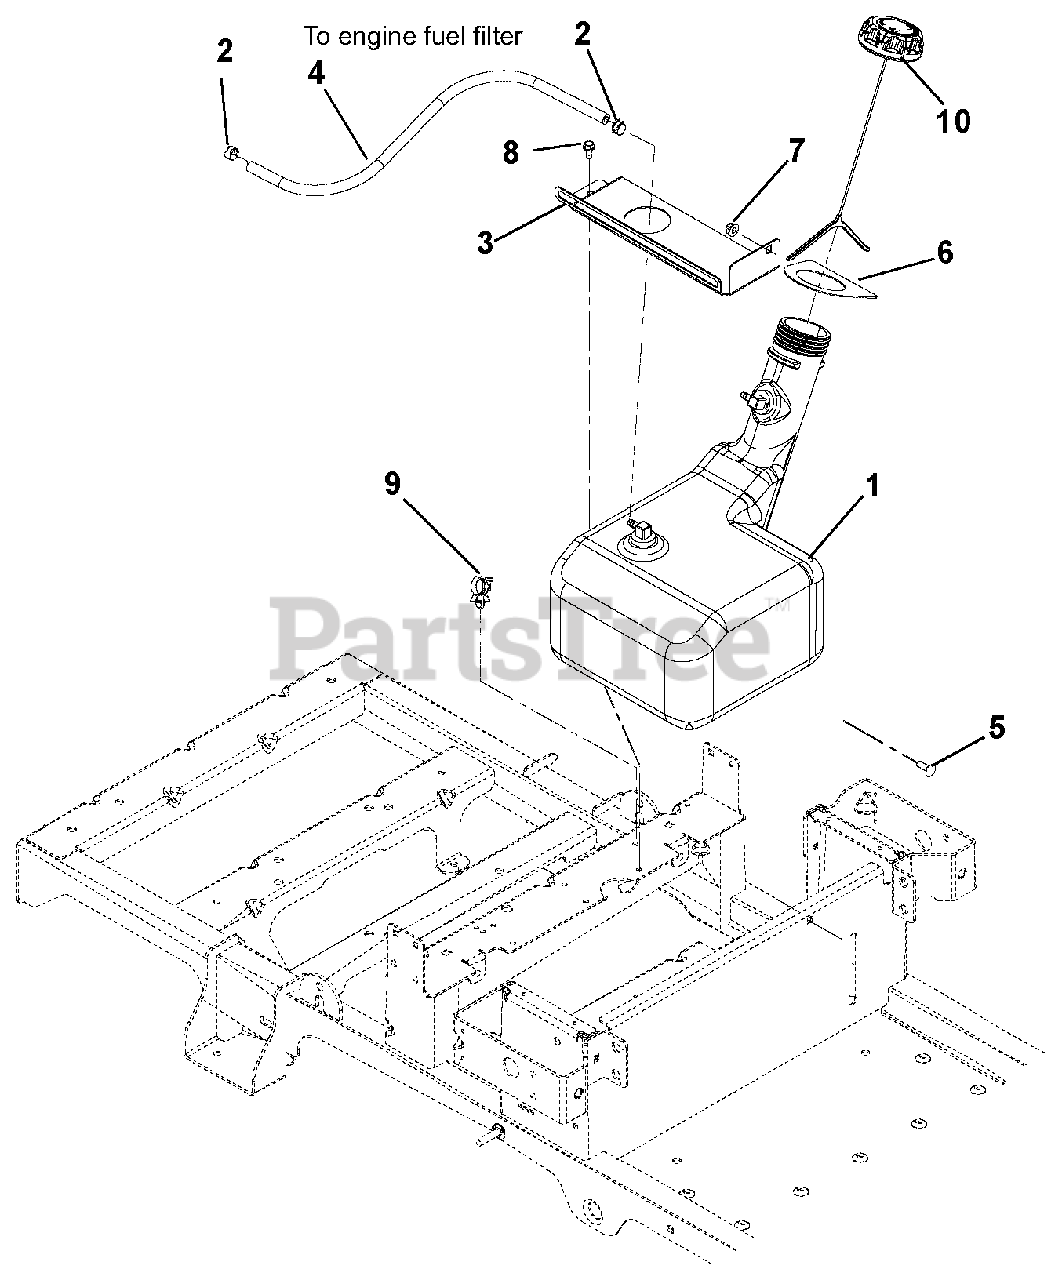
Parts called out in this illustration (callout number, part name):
1	FUEL TANK SUB ASSY ZT/ZOOM/WAW
1	TANK, ZOOM/WAW NON-PERM. FUEL
1	FUEL PICK UP TUBE
1	BSHG-FLG .375X1.062X.625 NITR
1	FITTING, 90 DEG FUEL-PLASTIC
2	CLAMP, FUEL LINE
3	BRKT, TANK STRAP
4	HOSE, .25 LOW-PERM BULK GAS
5	@BLT-RDHDSQNK .25-20X.75 G5YZ
6	SEAL-TANK NECK
7	@NUT-LK-NYL-FLG .25-20 YWZC
8	SCR-TAP .25-20X.50 HWH TR YWZ
9	WIRE CLIP
10	CAP, FUEL VENT-IN 2.25" RATCH.
